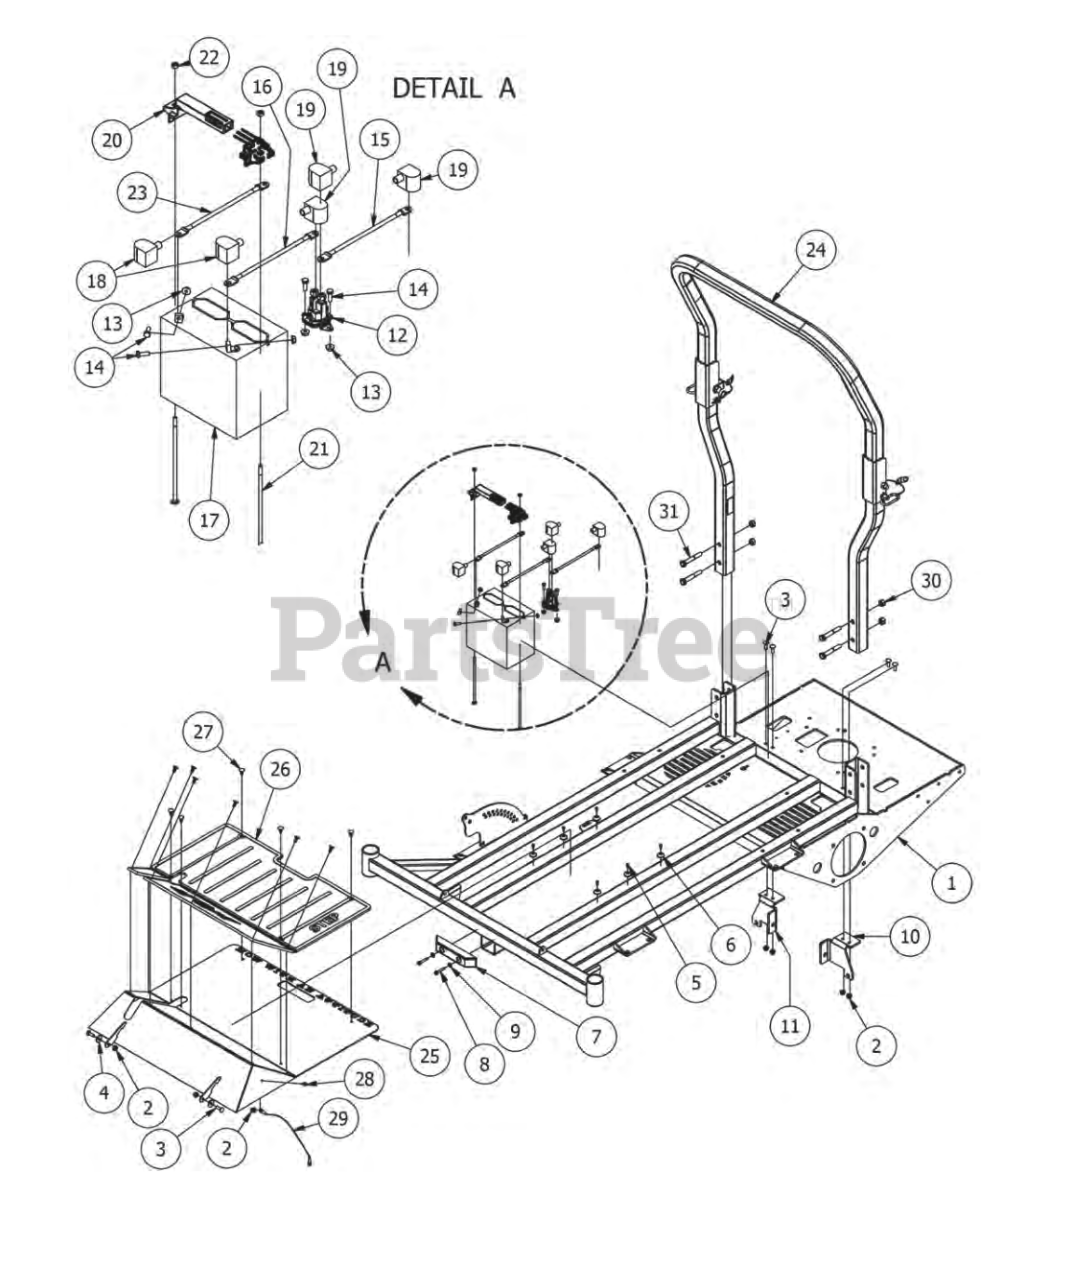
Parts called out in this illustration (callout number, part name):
1	2015 Standard/Extreme Outlaw Frame
2	5/16" Flange Nut Zinc W/Serrations
3	5/16" x 1" Carriage Bolt
4	.360 ID Plastic Washer
5	#10 x 1/2" Self Taping Screw
6	Button Bumper
7	8" Rubber Bumper
8	1/4" x 1 1/2" Self Tapping Screw
9	1/4" Flat Washer
10	Outlaw Brake Cable Mount Bracket (Right)
11	Outlaw Brake Cable Mounting Bracket (left)
13	1/4-20 Hex Flange Nuts Zinc w/Serrations
14	1/4-20 x 3/4 GR 5 Hex Bolts Zinc
15	red battery cable alternator to Started cable
16	12 in red battery cable
18	Black Boot For ground cable
20	Battery Hold Down
21	1/4-20 X 8 Carriage Bolt
22	1/4-20 Hex Nut
23	Starter to chassis cable
24	2015 Outlaw 2x2 Folding ROPS
25	Outlaw Floor Panel
26	Foot Assist Floor Mat
27	Ratchet Fastener
28	1/4" x 5/8" BS C/S 18-8 SS
29	Floor board Cable W/ Swivel Ends
30	1/2" Center Lock Nut
31	1/2-13 X 3.25 Hex Bolt - Grade 5
